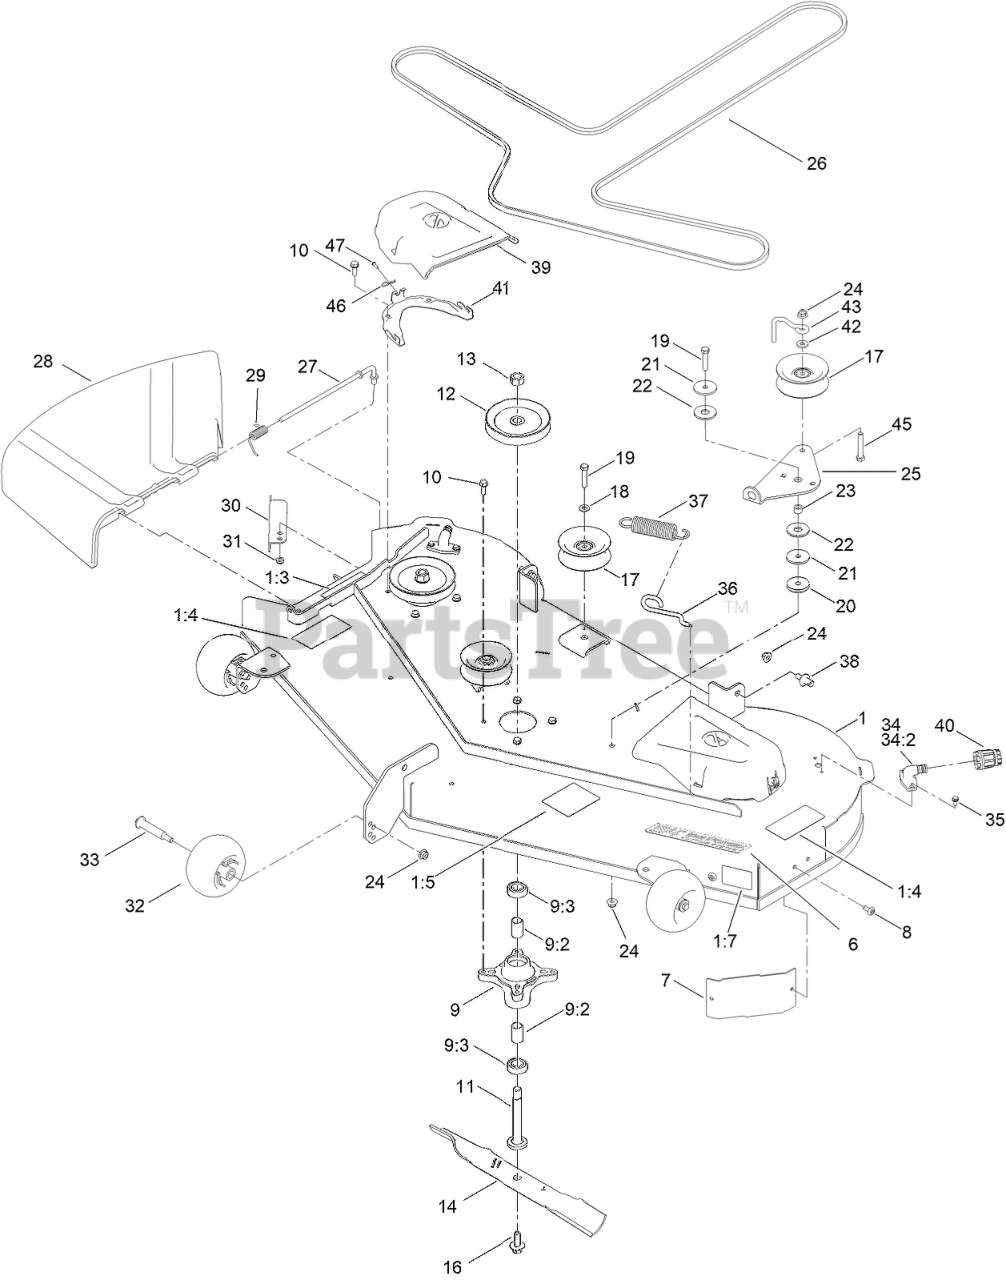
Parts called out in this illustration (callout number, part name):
1	54in DECK AND DECAL ASM
1:3	DECAL-DANGER
1:4	DECAL-DANGER, DECK
1:5	DECAL-ROUTING, BELT
1:7	DECAL-SCALP, ANTI
6	DECAL-DECK
7	BAFFLE-CORNER
9	SPINDLE ASM
9:2	SPACER
9:3	BEARING-BALL
10	SCREW-TAPTITE
11	SHAFT-SPINDLE
12	PULLEY ASM
13	NUT-HEX
14	BLADE-HI LIFT
16	BOLT-BLADE, SEMS
17	PULLEY-IDLER, FLAT
18	WASHER-FLAT
19	SCREW-HH
20	WASHER-PLAIN
21	WASHER-REBOUND
22	WASHER-FRICTION, COMPOSITE
23	SPACER
24	NUT-HF, NI
25	ARM-IDLER
26	BELT-V
27	ROD-PIVOT
28	DEFLECTOR-DISCHARGE
29	SPRING-TORSION
30	BAFFLE-CUTOFF
32	ROLLER-SCALP, ANTI
33	BOLT-SHOULDER
34	FITTING-WASHOUT
34:2	O-RING
35	SCREW-HWH
36	HOOK-RETURN SPRING
37	SPRING-EXTENSION
38	PIN-DECK
39	COVER-BELT
40	CONNECTOR-HOSE
41	BRACKET-COVER, BELT
42	SPACER-HUB, BLOWER
43	BELT GUIDE - IDLER
45	SCREW-HH
46	PIN-HAIR
47	SCREW
